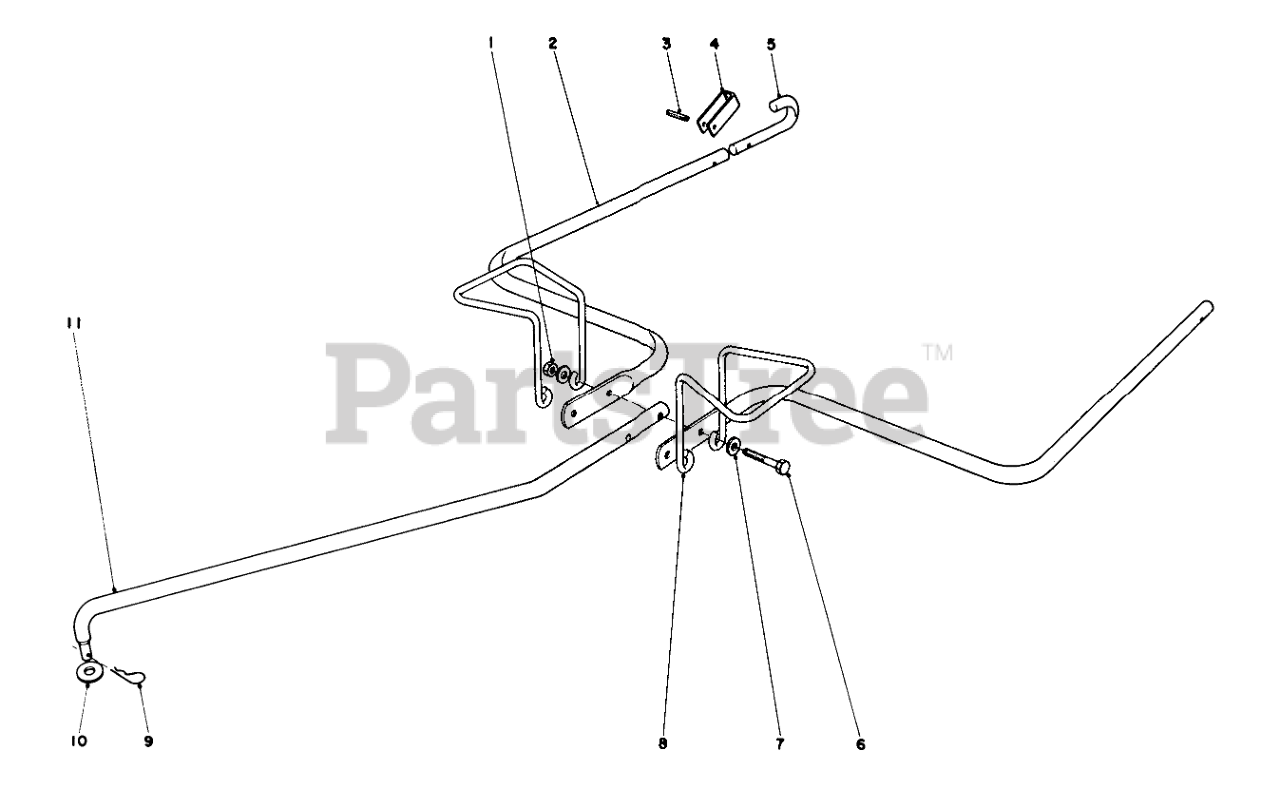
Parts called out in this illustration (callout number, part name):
1	NUT-LOCK, CONE
2	HITCH ARM
3	PIN-ROLL, SLOT
4	HITCH LOCK
5	HOOK HITCH ARM
6	SCREW-HH
7	WASHER-FLAT
8	Support Bag
9	PIN-COTTER
10	PUSH NUT
11	POLE HITCH
